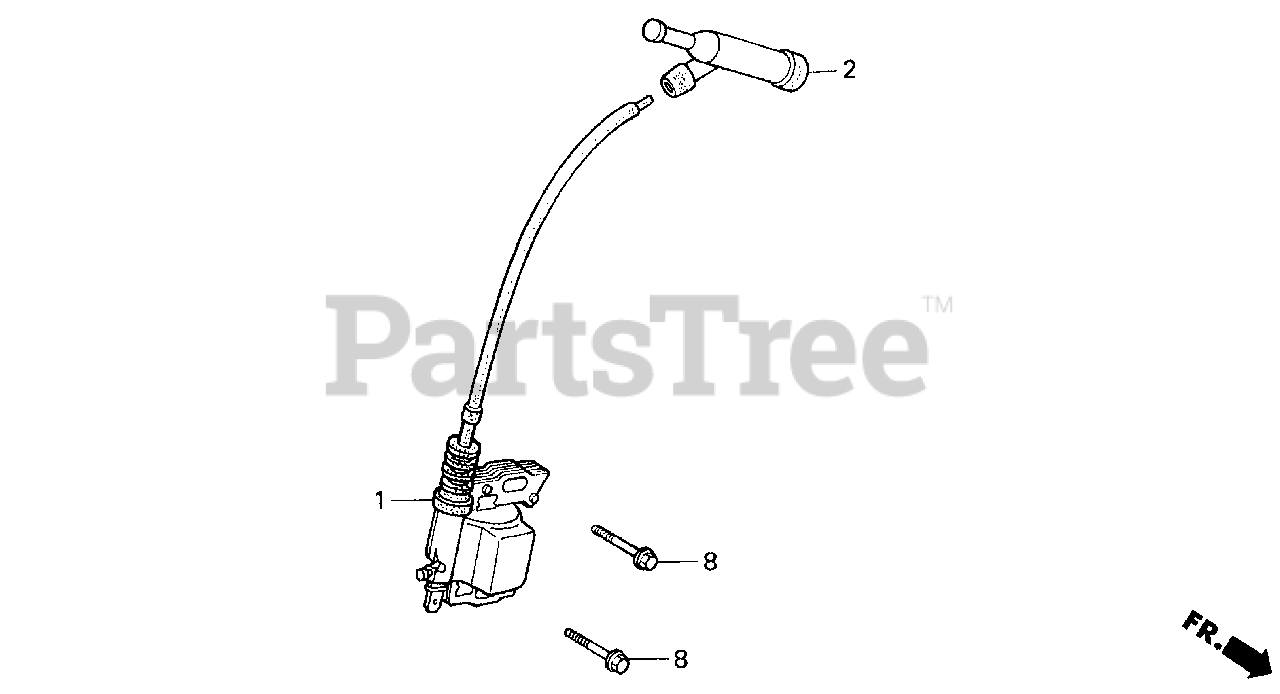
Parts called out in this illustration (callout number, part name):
1	COIL ASSY., IGNITION
2	CAP ASSY., NOISE SUPPRESSOR (NICHIWA Y-EZ RTFM256)
8	BOLT, FLANGE (6X25) (CT200)
